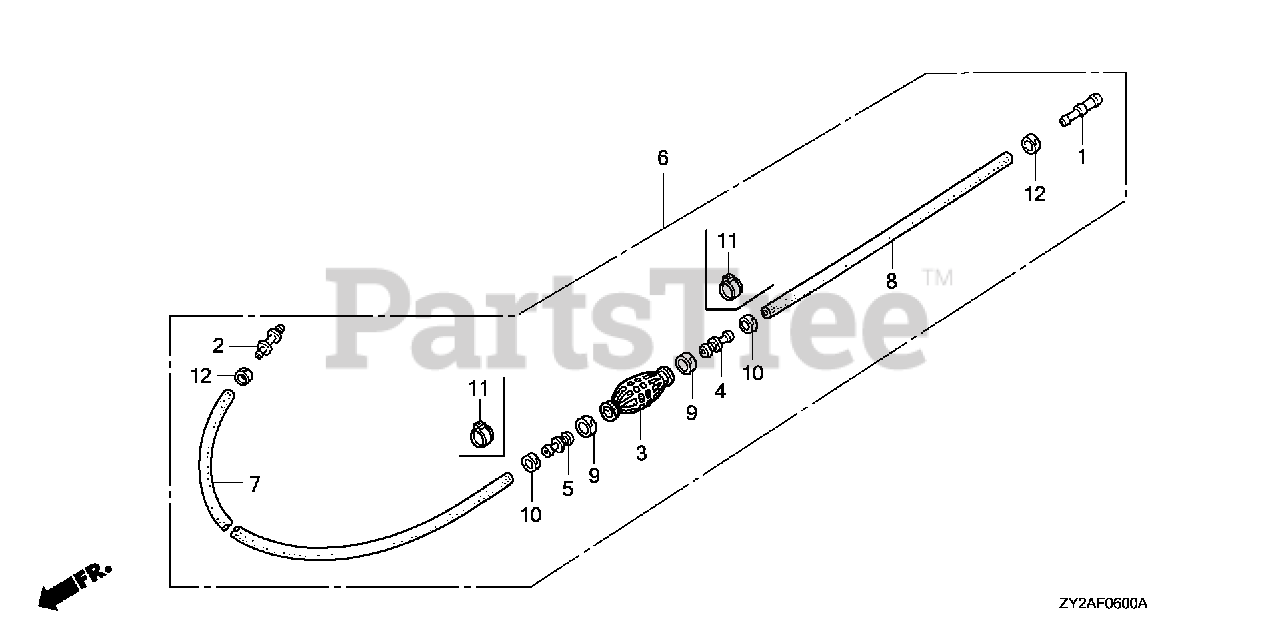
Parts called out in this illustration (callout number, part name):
1	JOINT, FUEL TUBE
2	JOINT, FUEL TUBE
3	BULB, PRIMER
4	VALVE, IN.
5	VALVE, OUTLET
6	TUBE ASSY., FUEL (JOINT TYPE)
7	TUBE, FUEL LONG (7.3X2000)
8	TUBE, FUEL SHORT (6.3X500)
9	BAND, TUBE CLIP (20MM)
10	BAND, TUBE CLIP (12.5MM)
12	BAND, TUBE CLIP (12.5MM)
